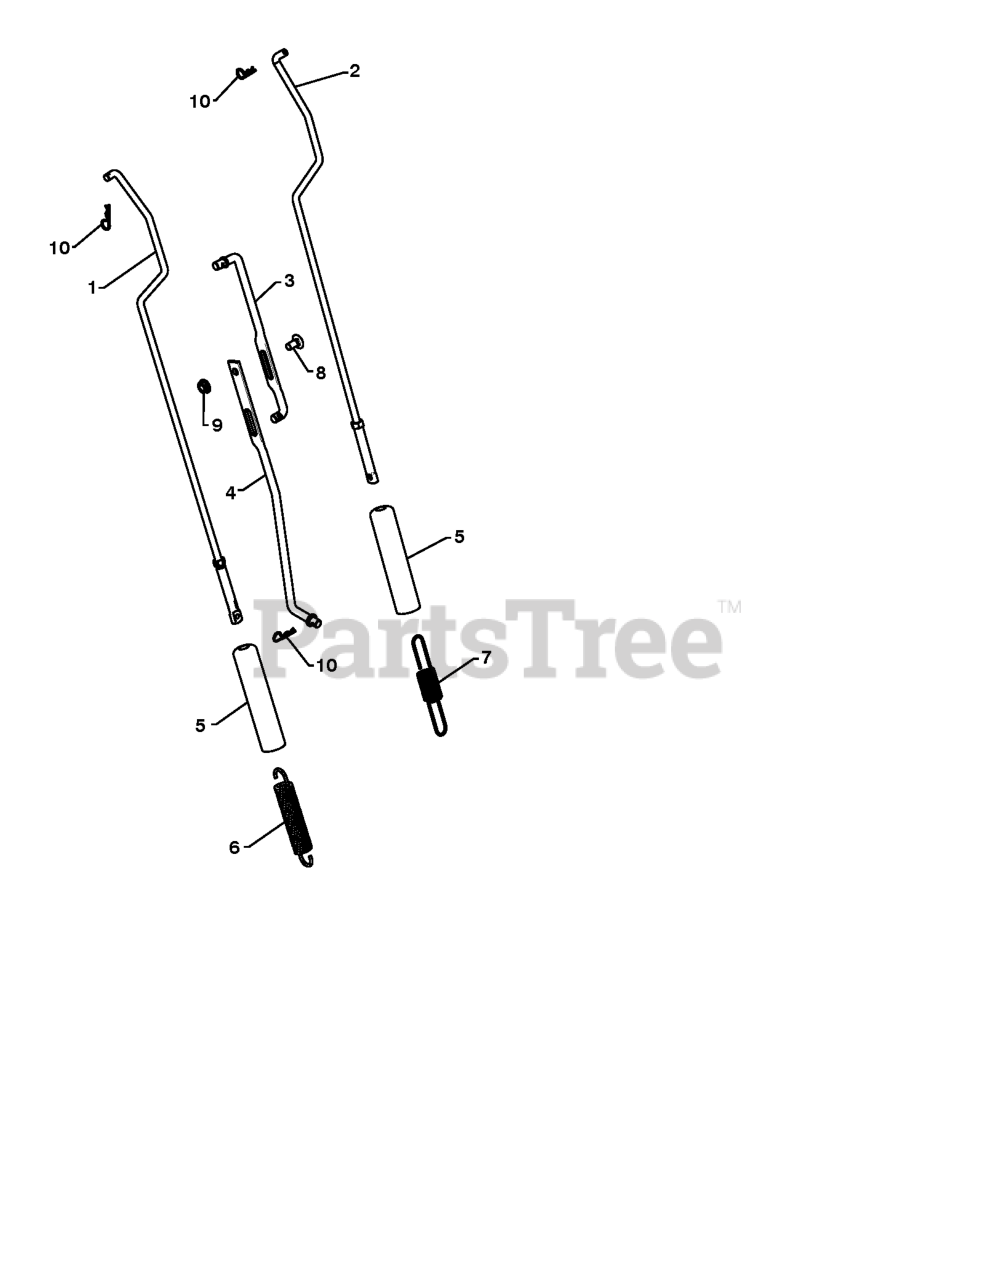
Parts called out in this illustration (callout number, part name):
5	CAP.ASSY.FUEL.3".N-EPA.GRY.498
7	Screw M10x25
8	LOCKNUT M6
